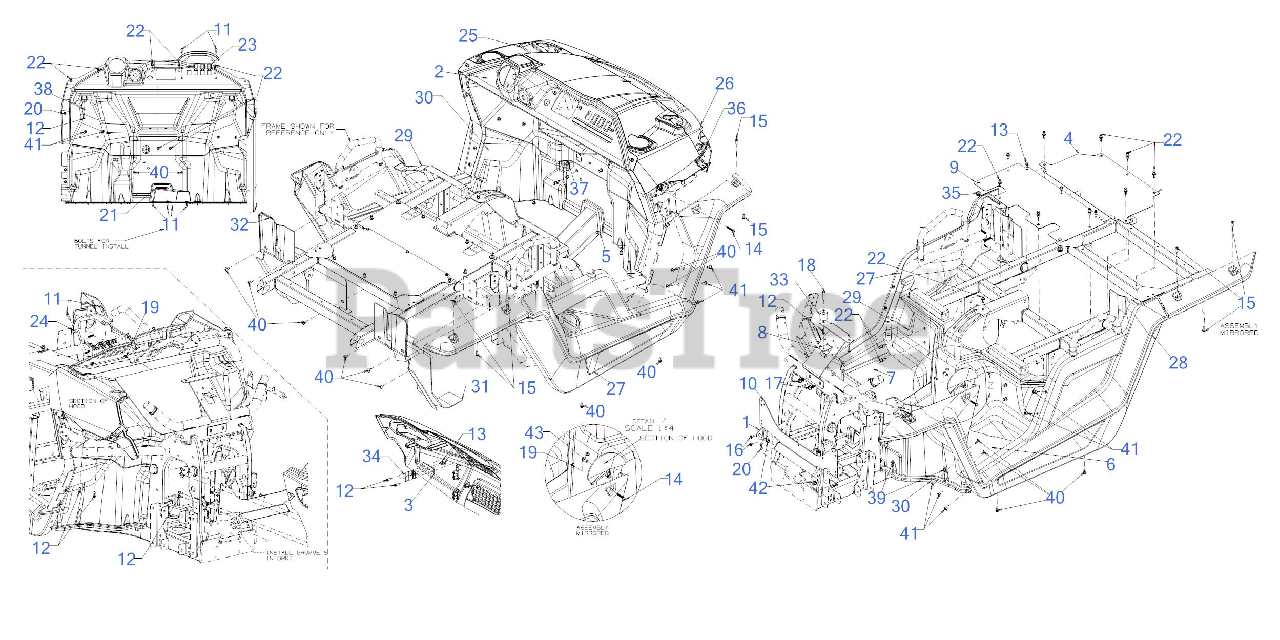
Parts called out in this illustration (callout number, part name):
1	GRILLE PIVOT WELD ASSEMBLY
2	UPPER DASH ASSEMBLY
3	GRILLE MOUNTING BRACKET
8	HOOD SUPPORT BRACKET
10	GRILLE MOUNTING BRACKET
11	SCREW 1/4-20 x 1.0
12	SCREW 1/4 x .750
13	SCREW 1/4-20 X.500
14	SCREW 1/4-20 x 1.50
15	SCREW-1/4-15 X 0.750 PHILLIPS
16	SCREW M6-1 x .625
17	SCREW 3/8-16 x 3/4
18	SCREW 1/4-20 X1.625
19	FLANGE LOCK NUT
20	BOW TIE COTTER PIN 1/4-5/16
21	BULB SEAL GASKET (.438")
22	PLASTIC RIVET
23	PANEL SWITCH PLUG
24	GRAB HANDLE
25	FRONT HOOD
26	PIVOT HOOD
27	MIDDLE FENDER (RH)
28	MIDDLE FENDER (LH)
29	FRONT SEAT COVER
30	UPPER FLOOR BOARD COVER
31	INNER FENDER (RH)
32	INNER FENDER (LH)
33	HOOD LATCH ROLLER
34	HOOD LATCH SPRING
36	HOOD STRAP
37	THROTTLE CABLE GROMMET
38	FLAT WASHER
39	SHOULDER SCREW
40	TORX SHOULDER SCREW 1/4-20
41	SHOULDER SCREW .375X.280:1/4-14
42	BUSHING .380 ID
43	SHOULDER SPACER
